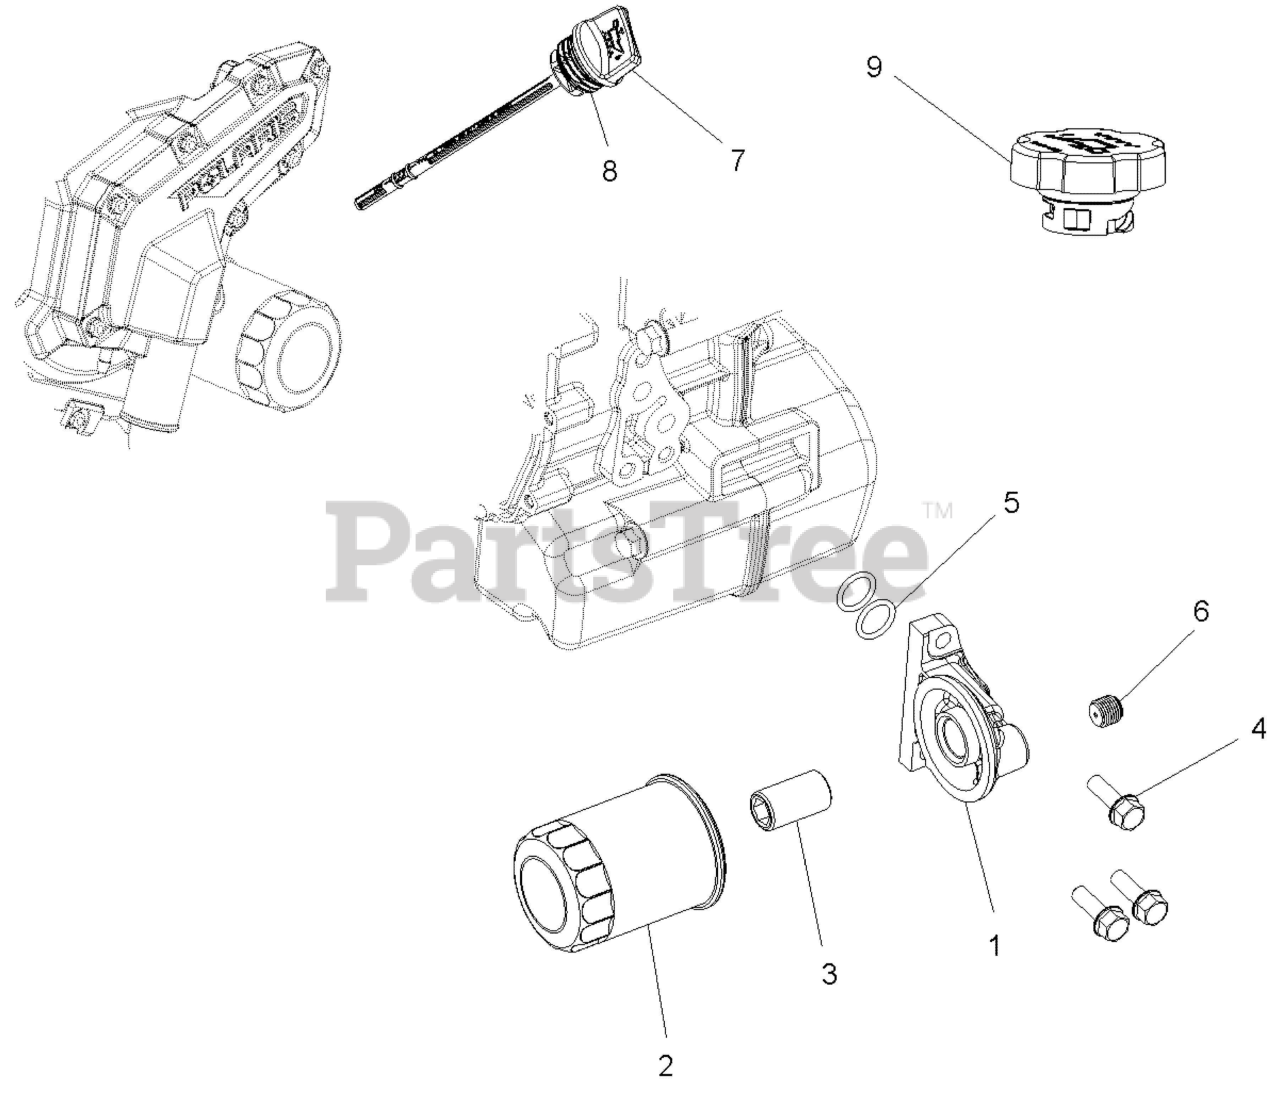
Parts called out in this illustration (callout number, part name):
1	ADAPTER, OIL FILTER, MACH
2	FILTER-OIL,10 MICRON,(12)
3	ADAPTOR, FILTER, STRAIGHT
5	O-RING-17.12X2.62
6	PLUG,HEX SCKT W/O-RING,M14X1.5
7	DIPSTICK-OIL FILL
8	O-RING-26.65X2.62,0600083
9	ASM-OIL FILL CAP
9	O-RING-FILL CAP
